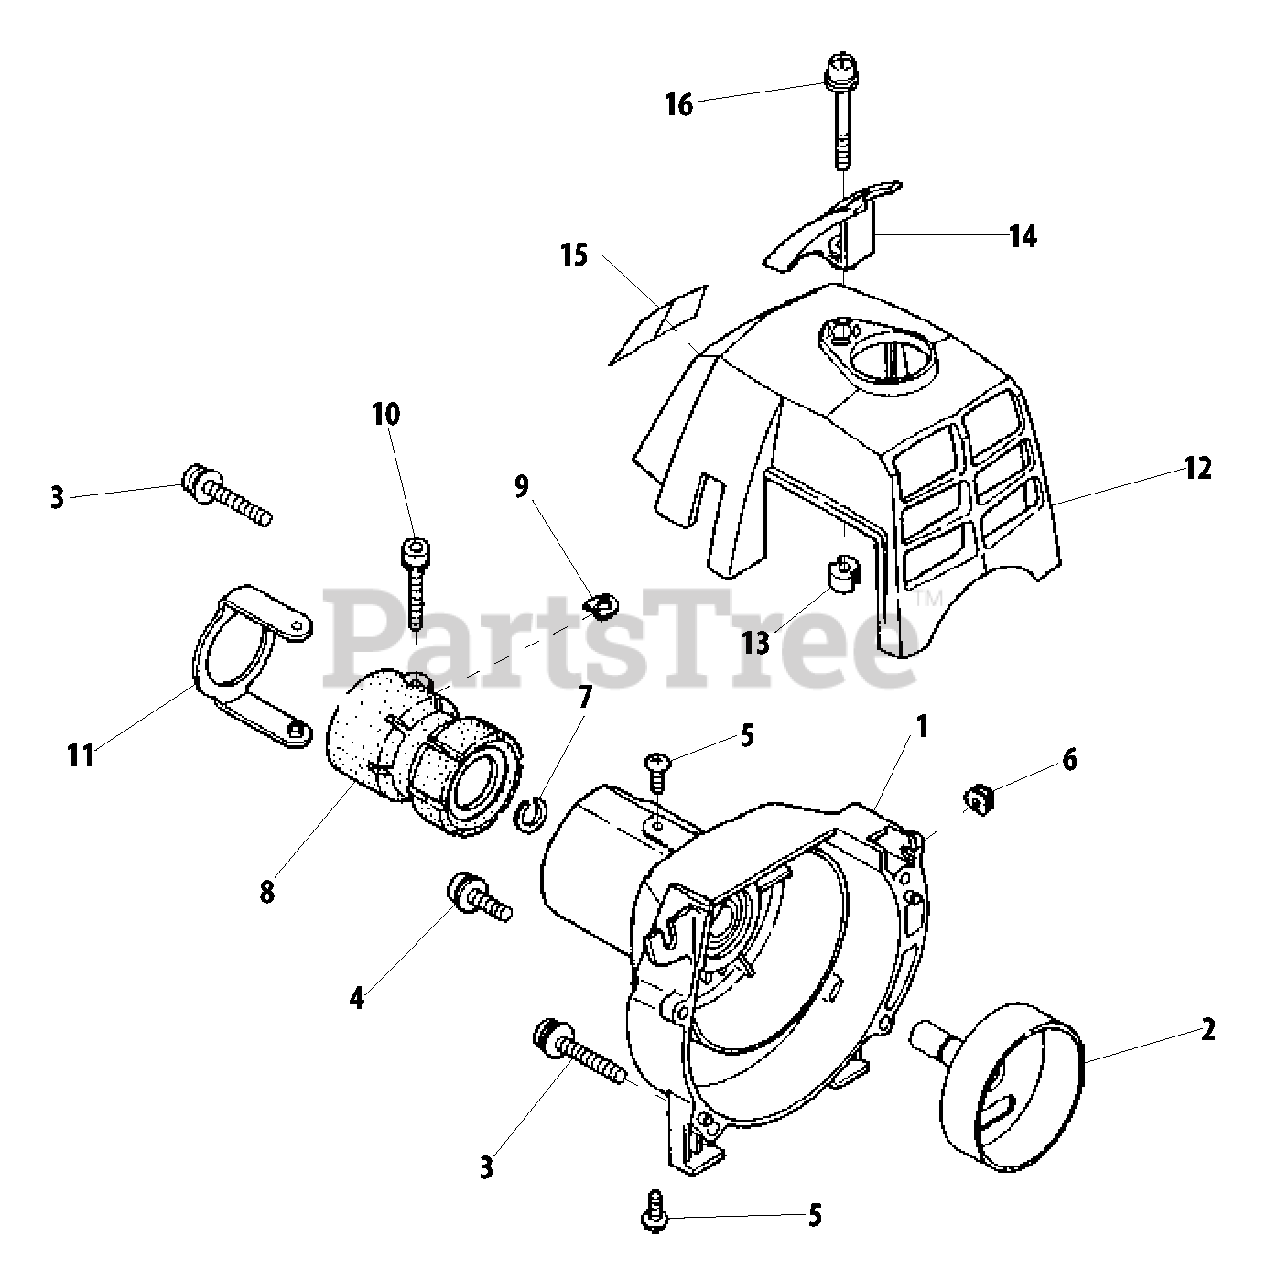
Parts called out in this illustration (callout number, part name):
1	COVER, FAN
2	DRUM, CLUTCH
3	SCREW - 5X30
4	SCREW - 5X16
5	SCREW - 4X8
6	GROMMET
7	RING, RETAINING
8	CLAMP, MAIN PIPE
9	SHIM
10	SCREW - 5X22
11	BRACKET
12	COVER, ENGINE
13	INSULATOR
14	PROTECTOR
15	LABEL - MODEL
16	SCREW
